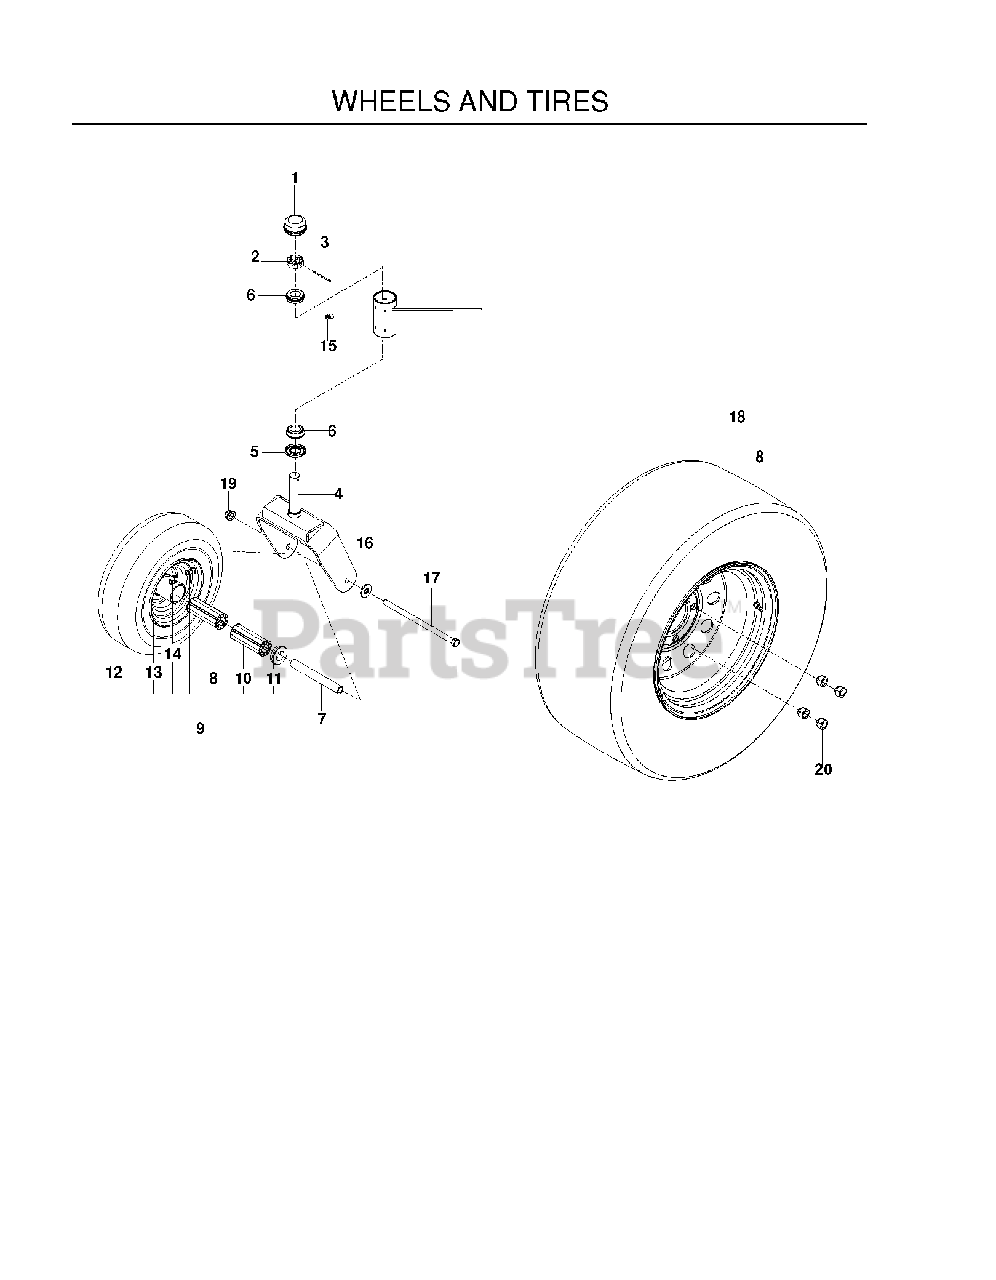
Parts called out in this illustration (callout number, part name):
1	GREASE CAP
2	NUT 1"C HEX SLOTTED
4	YOKE, CASTER, BLUE
6	TAPERED ROLLER BRG
7	SPACER, PIVOT
8	VALVE STEM TR-412
9	ASM, TIRE
10	ROLLER BEARING-CAGED 3 1/4'
11	BEARING RETAINER
12	TIRE, 13 X 6.50 - 6, 4 PLY
13	WHEEL, 6 X 4.50
14	ZERK
16	WASH USS FLAT 1/2
17	HEX SCREW 1/2-13 X 9.5 GR5
18	REAR TIRE ASSY
19	NUT, 1/2-13 HEX FLG NYLOC ZD
20	LUG NUT 1/2F
